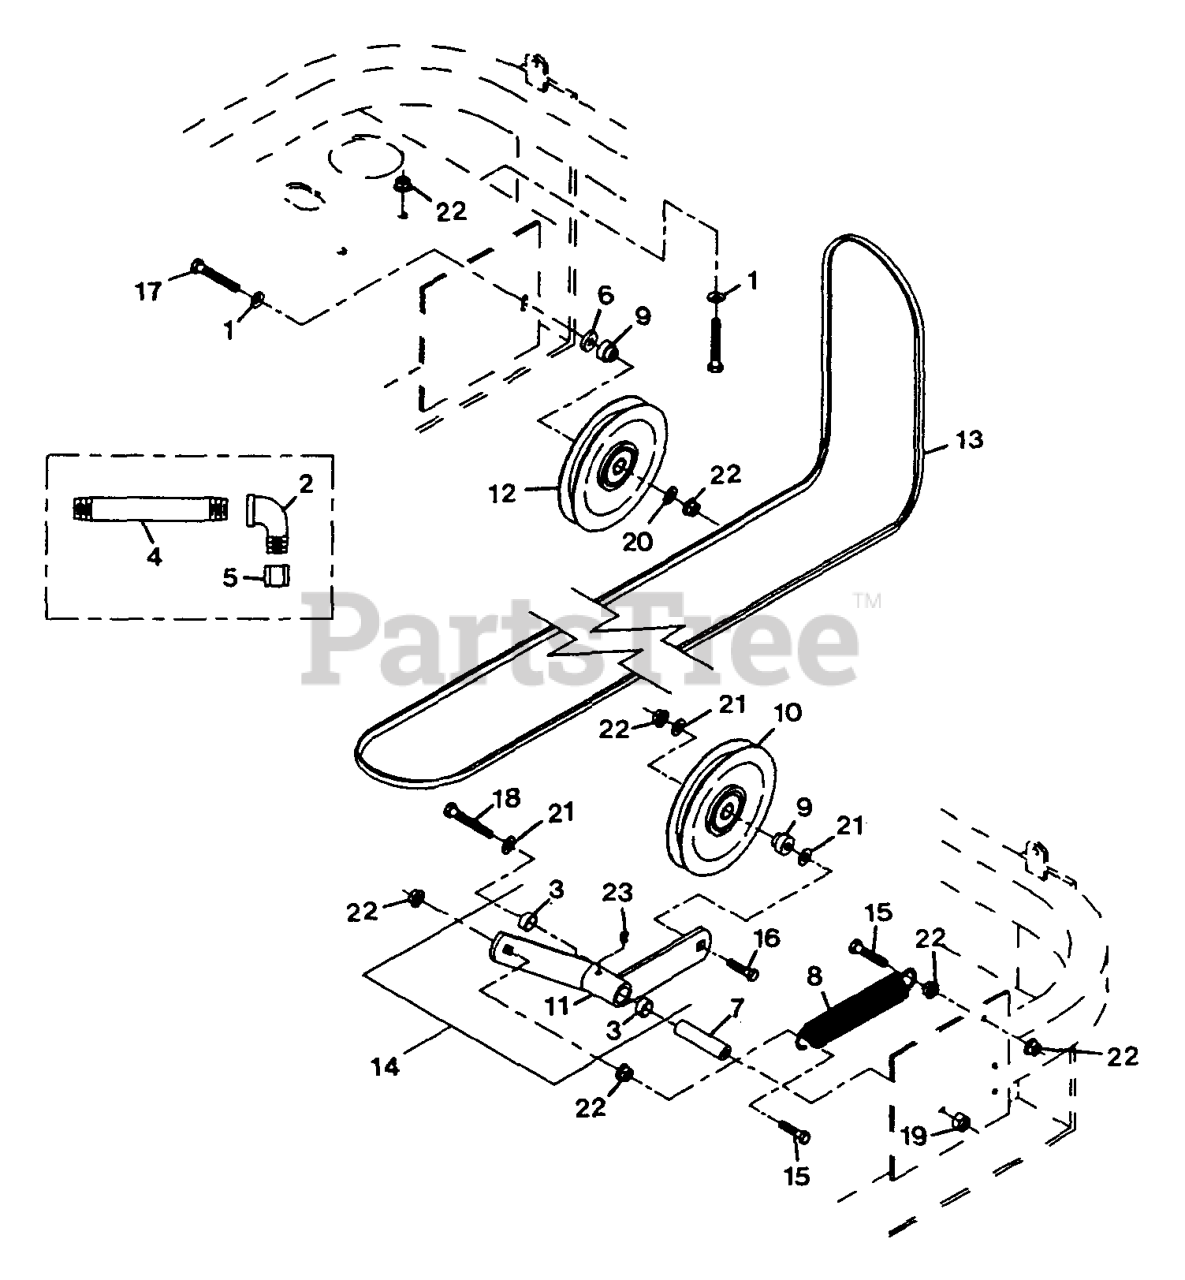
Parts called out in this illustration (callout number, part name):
2	ELBOW-90 DEG
3	SLEEVE-BEARING
4	NIPPLE
5	CAP-HEX
7	BUSHING-PIVOT, IDLER
8	SPRING-EXTENSION
9	BUSHING-IDLER
10	PULLEY-IDLER
12	PULLEY-IDLER
13	BELT,MULE DRIVE
18	SCREW-HH
